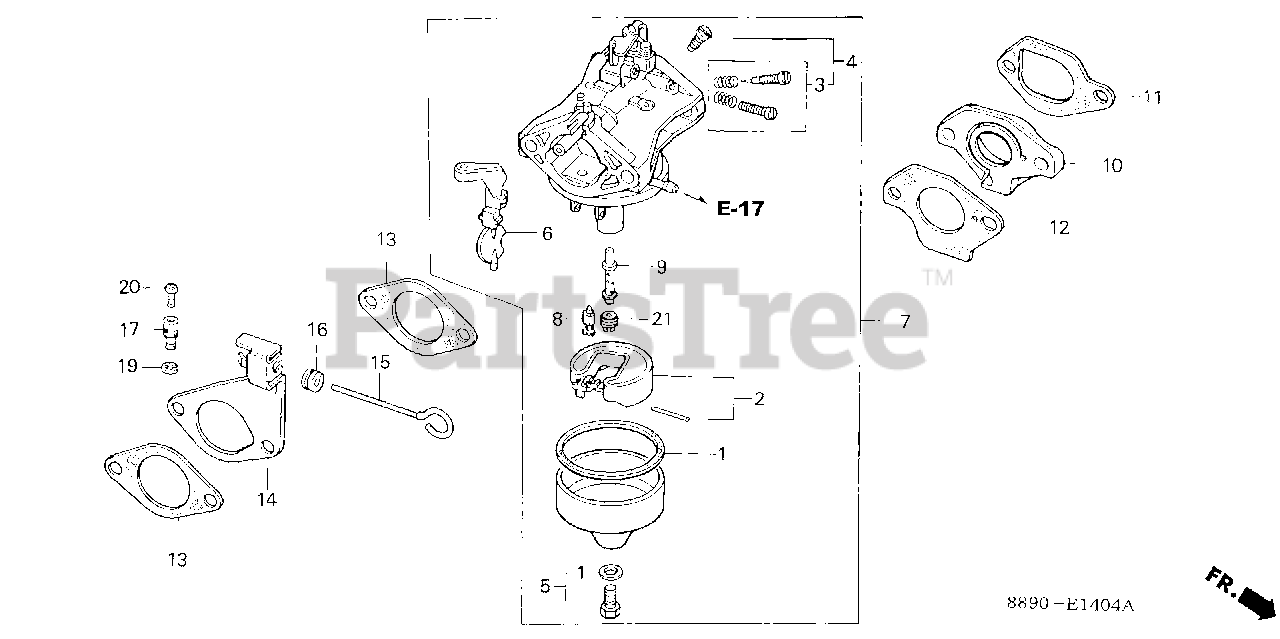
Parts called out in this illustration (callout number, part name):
1	GASKET SET
2	FLOAT SET (CARBURETOR NO.)
3	SCREW SET A
4	SCREW SET A (CARBURETOR NO.)
5	SCREW SET B (CARBURETOR NO.)
6	CHOKE SET (CARBURETOR NO.)
7	CARBURETOR ASSY. (BB33A B)
8	VALVE, FLOAT (CARBURETOR NO.)
9	NOZZLE, MAIN (CARBURETOR NO.)
10	INSULATOR, CARBURETOR
11	GASKET, INSULATOR
12	GASKET, CARBURETOR
13	GASKET, AIR CLEANER
14	STAY, CHOKE CONTROL (NOT AVAILABLE)
15	ROD, CHOKE CONTROL (NOT AVAILABLE)
16	GROMMET, CHOKE ROD
17	HOLDER, CABLE
19	CIRCLIP (5MM)
20	SCREW, PAN (4X8)
21	JET, MAIN (#75) (CARBURETOR NO.)
21	JET, MAIN (#78) (CARBURETOR NO.)
21	JET, MAIN (#80) (CARBURETOR NO.)
21	JET, MAIN (#82) (CARBURETOR NO.)
21	JET, MAIN (#85) (CARBURETOR NO.)
